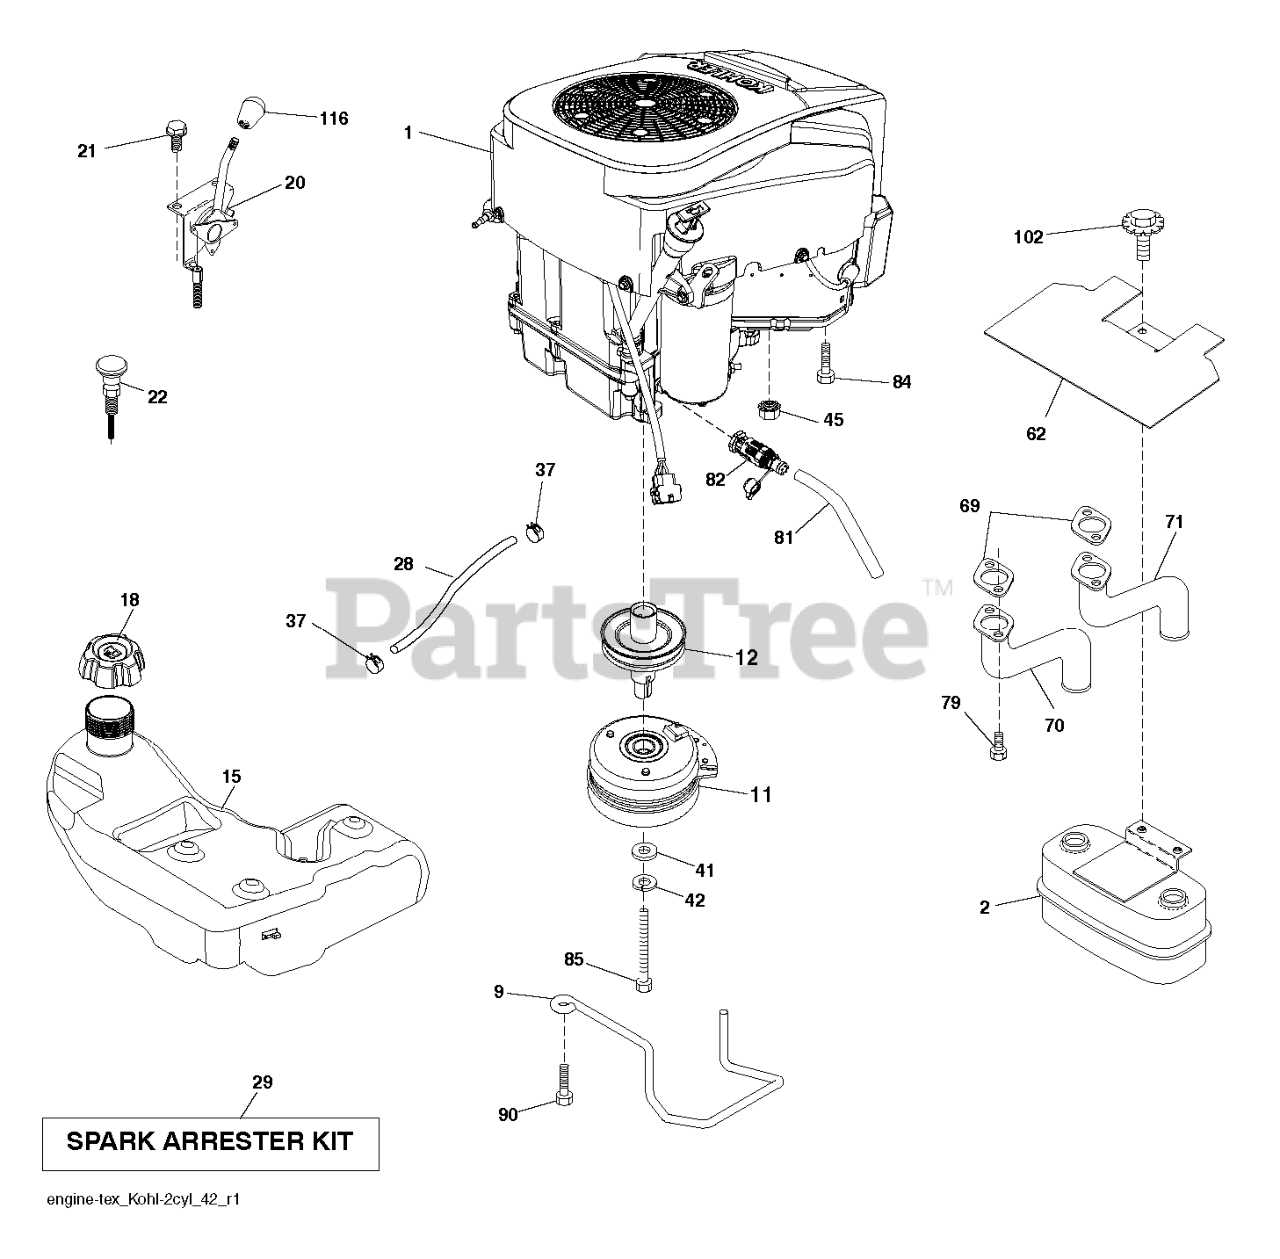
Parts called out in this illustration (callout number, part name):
2	MUFFLER.ASM.TWN.EXTNDED.DFLCTR
9	KEEPER.BELT.ENGINE.4.2
11	CLUTCH. 5.0 PD. 2.5 OFFSET
12	PULLEY.EXTENDED.SHAFT.GROUND
15	RP_TANK.ASSY.3.GAL.EPA
18	CAP ASSY FUEL 3" GRAY
20	CONTROL.THROTTLE.PRO.KOHLER
21	SCREW.#10 X 0.750.BOS
22	CONTROL.CHOKE.ERGO.PUSH-IN.BLA
28	LINE.FUEL.64"REAR.EMIS
29	KIT.SPARK ARRESTOR 794945 B&S
37	HOSE CLAMP
42	LOCKWASHER
45	NUT
62	SHIELD.HEAT.MUFFLER
70	TUBE.EXHAUST.LH.FR961/FR730
71	TUBE.EXHAUST.RH.FR961/FR730
79	SCREW.SOCKET HD.5/16-1
81	TUBE, DRAIN OIL ASM.
82	VALUE.OIL.DRAIN
84	SCREW 3/8-16X1
85	BOLT.HEX.7/16-20 X 5
90	SCREW 3/8-16X1
102	SCREW
116	KNOB - SHIFT
